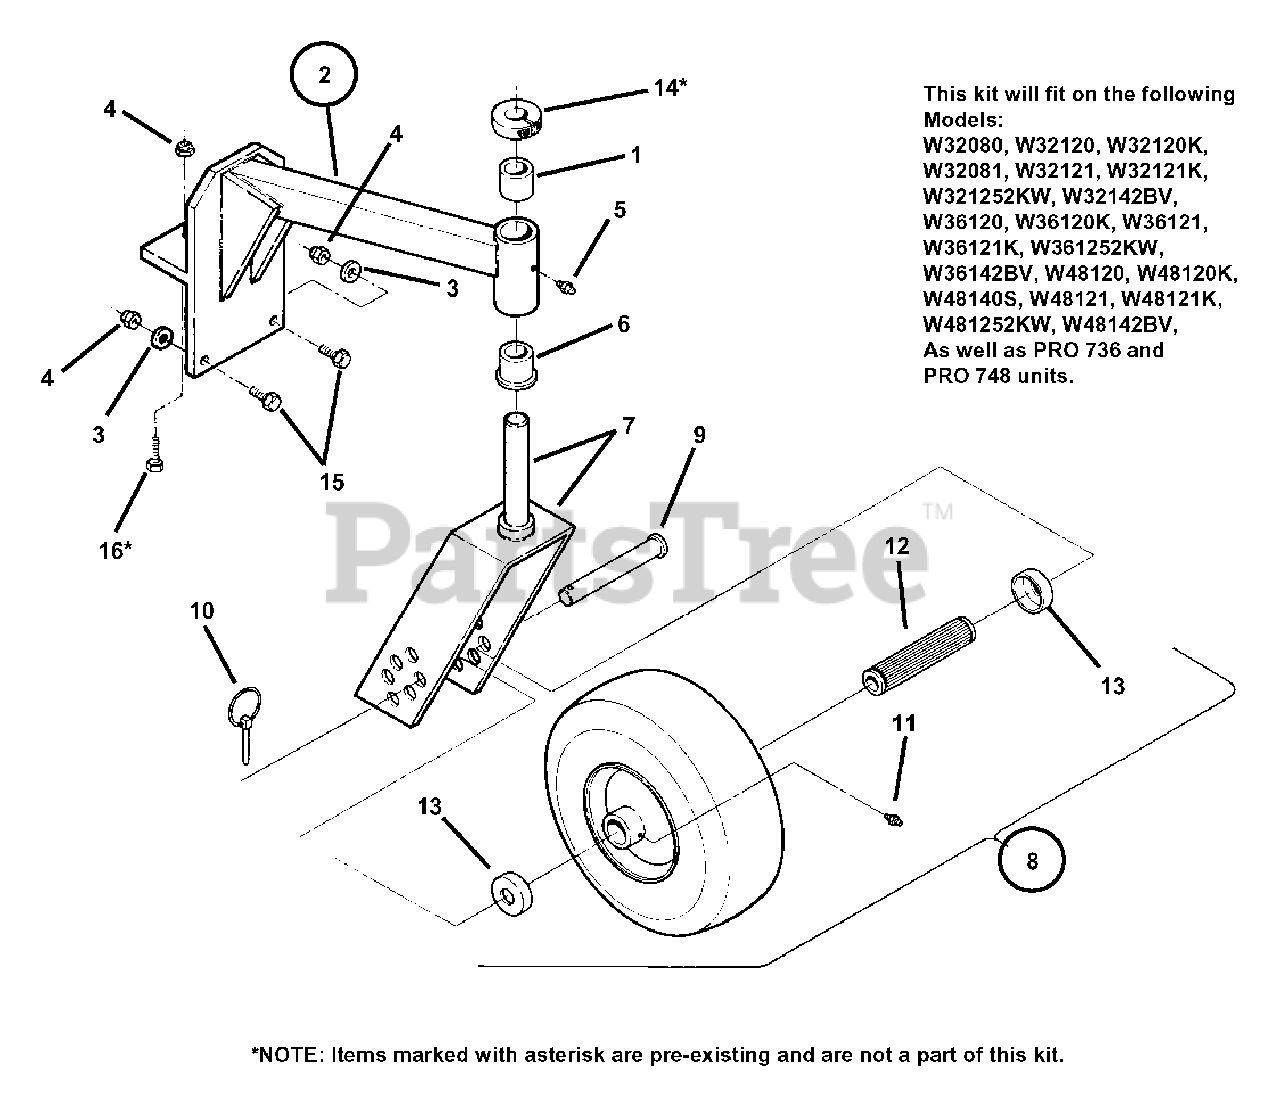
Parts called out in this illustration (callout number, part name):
1	BUSHING, Straight
2	SUPPORT, Caster w/Bushings (7-6514 & 7-6515)
3	WASHER, 3/8" Flat
4	NUT, 3/8-16 Hex Nyloc
5	FITTING, Lube, 1/8 NPT Straight
6	BEARING, Flange Thrust(powdered metal)
7	YOKE, Caster (weldment)
8	ASSEMBLY, Semi-Pneumatic Tire
9	AXLE, Caster
10	LYNCH PIN, 3/16" Diameter
11	FITTING, Lube, 1/4-28, Straight
12	BEARING, Roller
13	CAP, End
14	COLLAR, Clamp 7/8" (existing)
15	SCREW, 3/8-16 x 1-14" Hex Head Cap
16	BOLT, 3/8-16 x 1-3/4" Hex Head Cap (existing)
